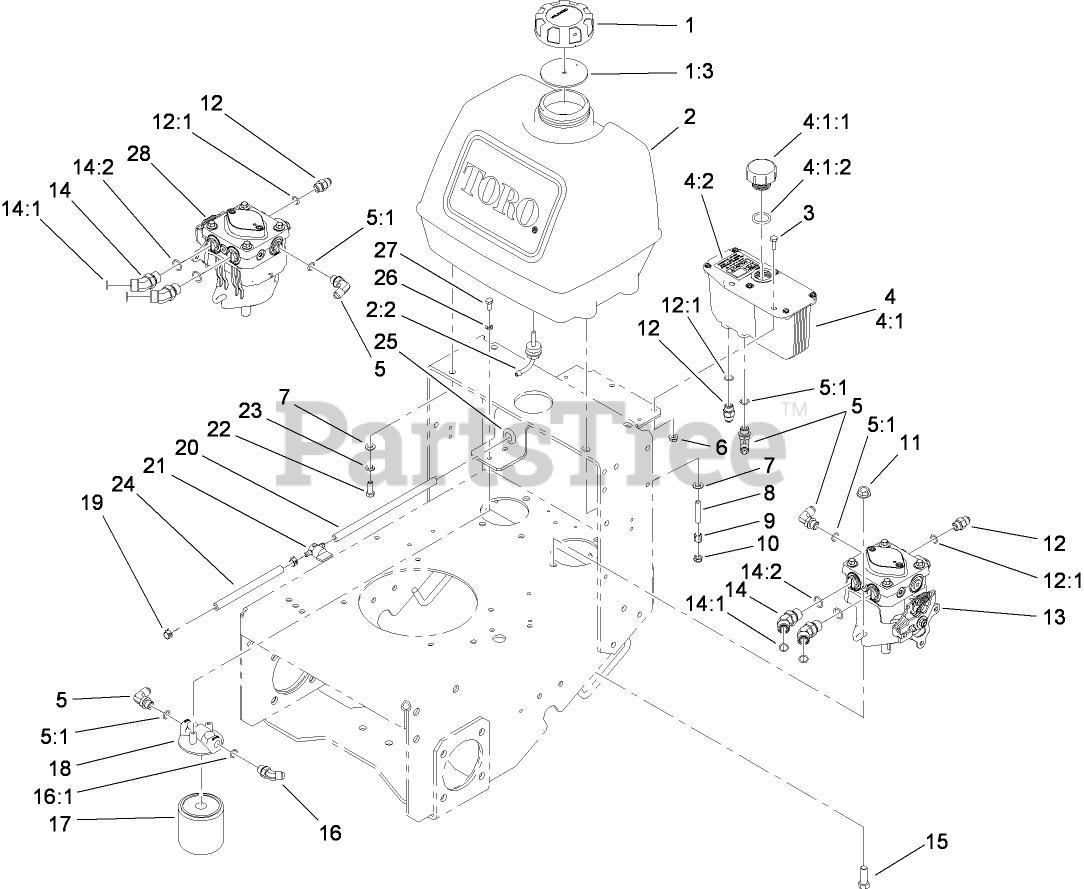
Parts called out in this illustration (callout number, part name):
1	GAS CAP ASM
1:3	GASKET-CAP, GAS
2	FUEL TANK ASM
2:2	FITTING-FUEL, BULKHEAD
3	SCREW-HH
4	HYD Reservoir ASM
4:1	Reservoir-HYD
4:1:1	CAP-RESERVOIR, HYD
4:1:2	GASKET-CAP
4:2	DECAL-TANK, HYD
5	FITTING-ELBOW, 90 DEG
5:1	O-RING
6	NUT-HF
7	WASHER-PLAIN
8	STUD-THREADED
9	SPRING-TANK, FUEL
10	NUT-LOCK, NI
11	NUT-HF
12	FITTING-STRAIGHT
12:1	O-RING
13	PUMP-HYD, LEFT
14	FITTING-HYD, 45 DEG
14:1	O-RING
14:2	O-RING
15	SCREW-HH
16	FITTING-ELBOW, 45 DEG
16:1	O-RING
17	FILTER-OIL, HYD (WINTER)
17	FILTER-OIL, HYD
18	HEAD-FILTER
19	CLAMP-HOSE
20	HOSE-FUEL
21	VALVE-FUEL
22	SCREW-HH
23	WASHER-LOCK
24	HOSE-FUEL
25	GROMMET
26	WASHER-LOCK
27	SCREW-HH
28	PUMP-HYD, RIGHT
